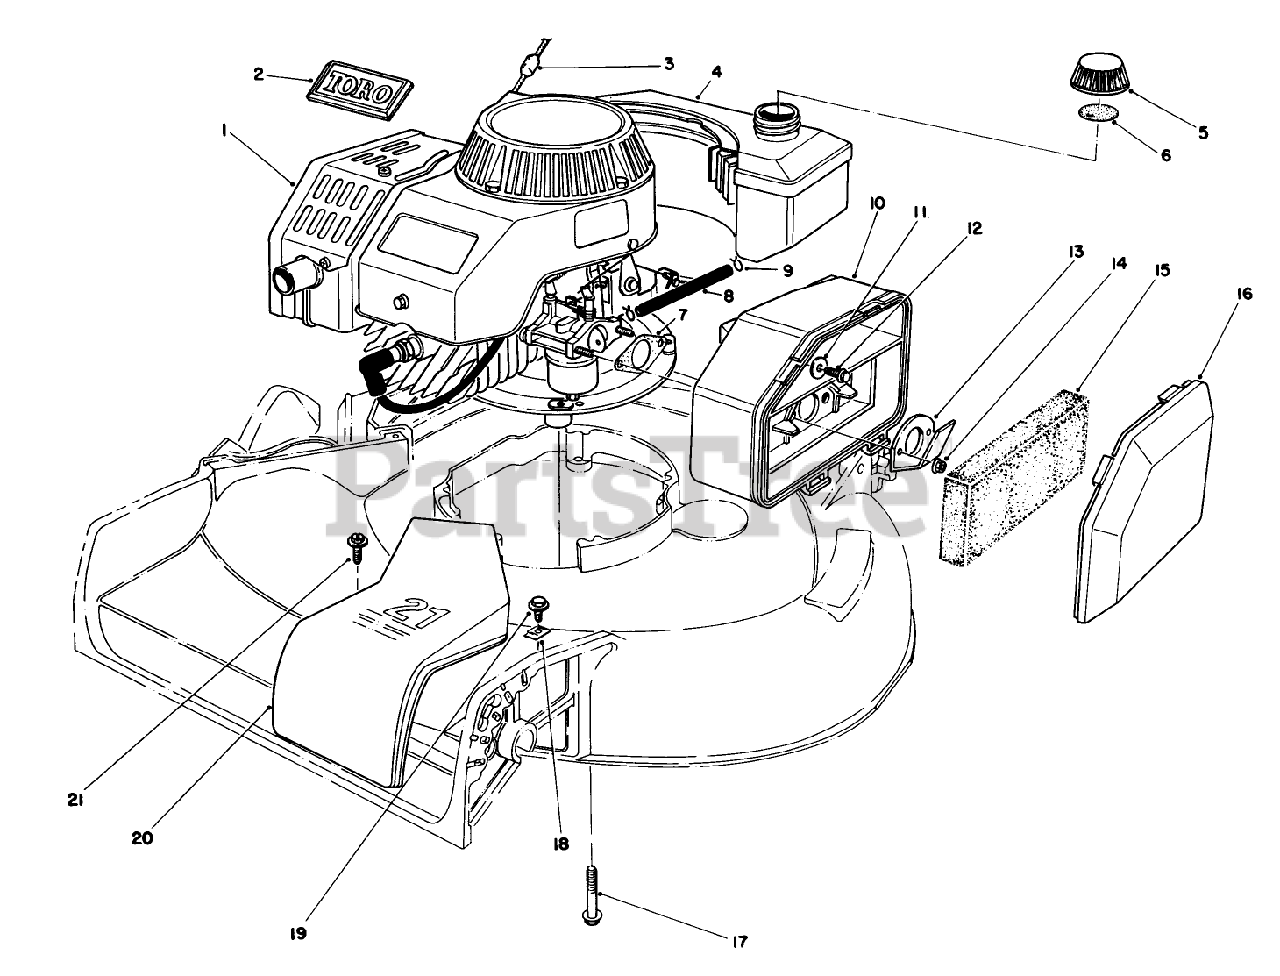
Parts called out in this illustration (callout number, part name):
3	STOP-ROPE
5	GAS CAP ASM 50:1
6	GAS CAP GASKET
7	GASKET-AIR CLEANER
8	FUEL LINE
9	CLAMP-HOSE
10	AIR CLEANER
11	WASHER-FLAT
12	SCREW-HH
13	SPIT BACK DEFLECTOR
15	FILTER
19	SCREW-THD ROLL, HWH
20	BELT COVER 21" S D
21	SCREW
